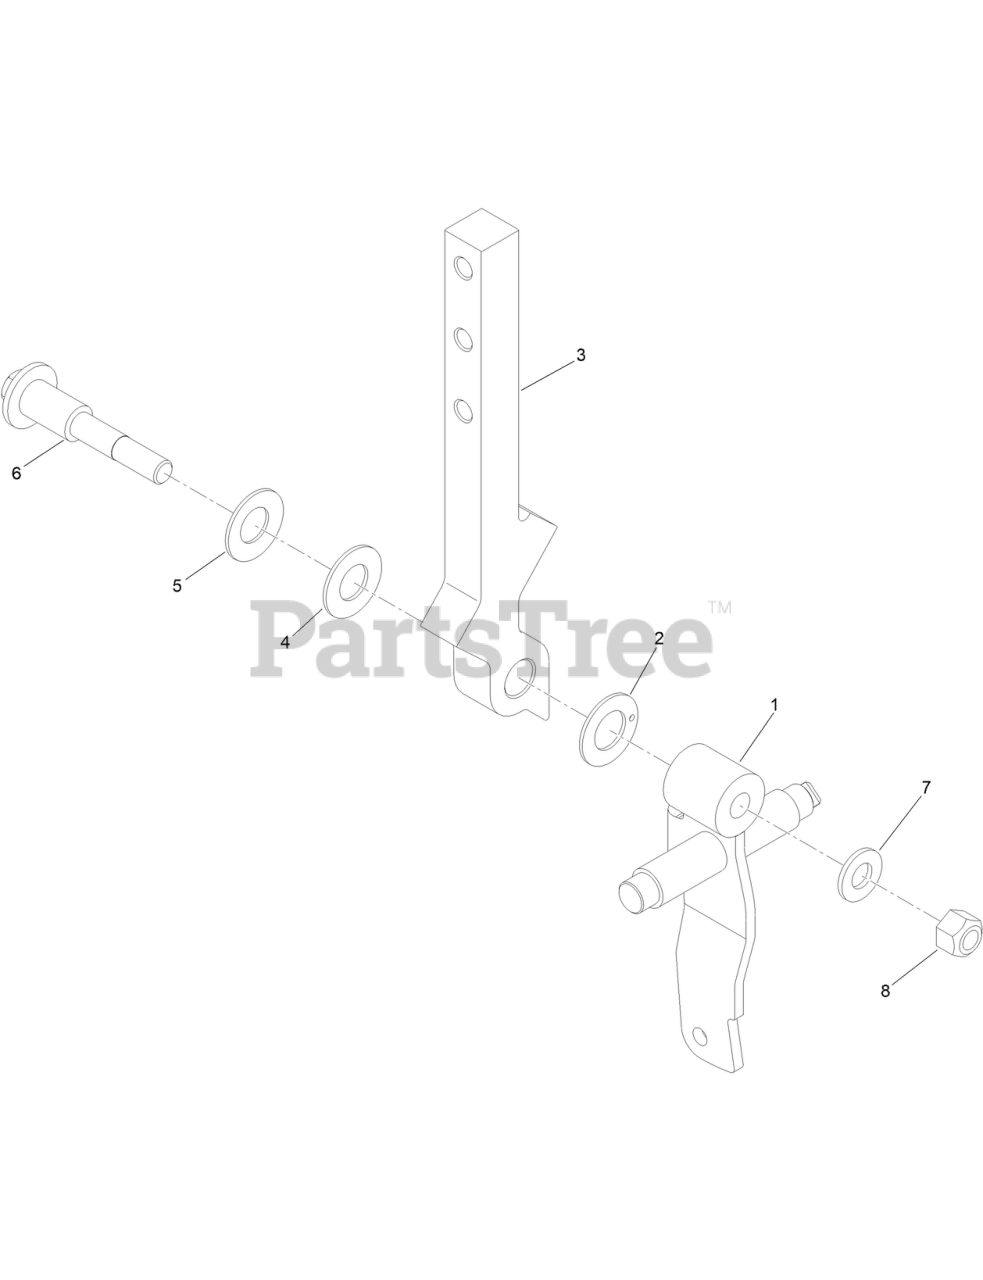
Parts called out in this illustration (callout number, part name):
1	RH CTRL ARM ASM
2	WASHER-FRICTION
3	ARM-CONTROL
4	WASHER
5	WASHER-BELLEVILLE
6	BOLT-PIVOT
7	WASHER-FLAT
8	NUT-LOCK, CONE
